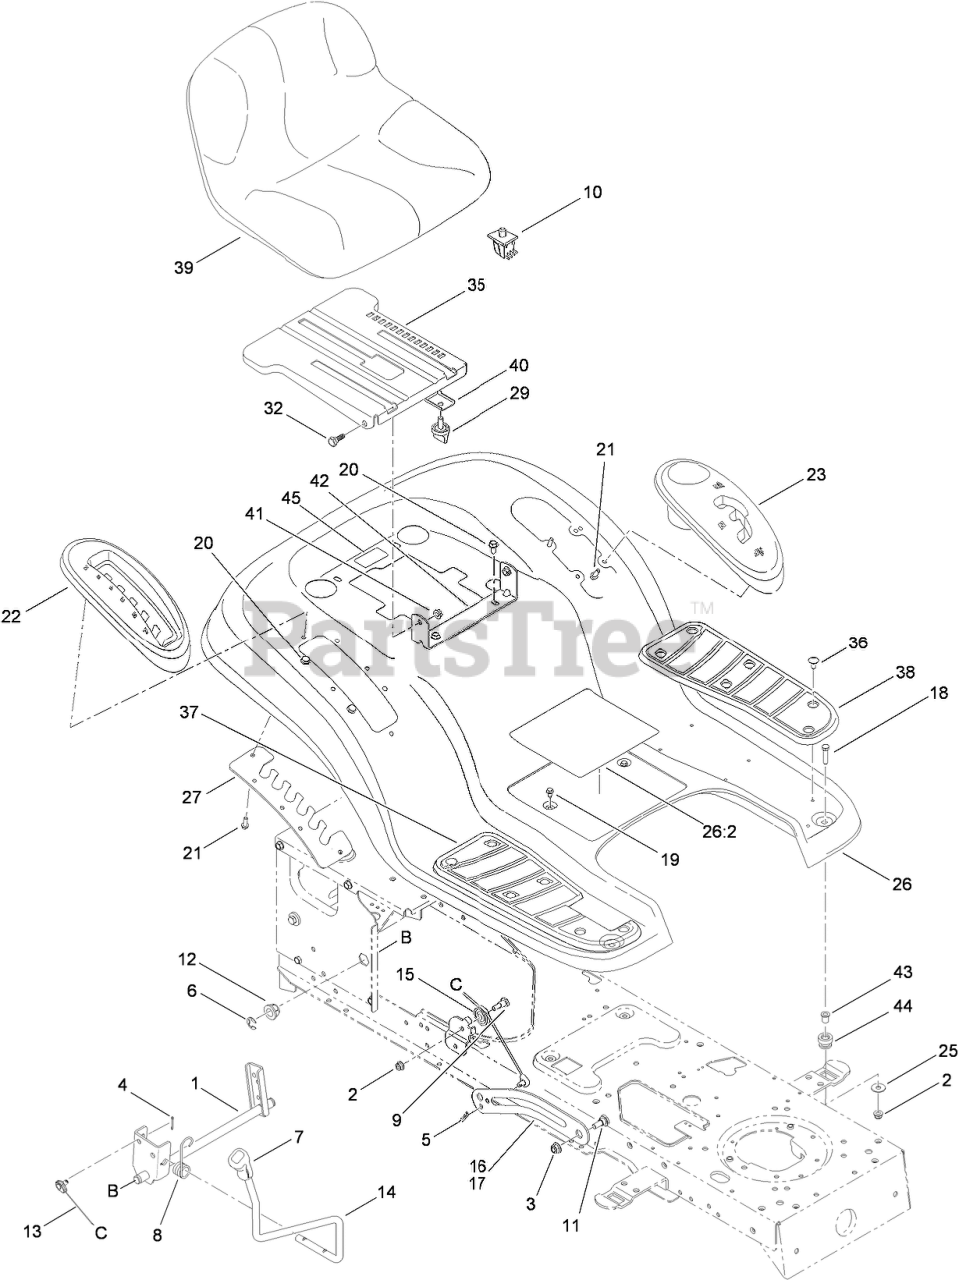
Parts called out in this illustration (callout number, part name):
1	LIFT SHAFT ASM
2	NUT-LOCK, FLANGE
3	NUT-LOCK, FLANGE
4	PIN-COTTER
5	PIN-COTTER
6	RING-E
7	GRIP-HANDLE
8	SPRING-TORSION
9	BOLT-SHOULDER
10	Switch-Seat
11	BOLT-SHOULDER
12	BEARING-FLANGE
13	CABLE-LIFT
14	HANDLE-LIFT
15	PULLEY-ROLLER
16	ARM-LIFT, RH
17	ARM-LIFT, LH
18	SCREW-HH
19	SCREW-HWHTF
20	SCREW-TAP
21	SCREW-TAP
22	COVER-LIFT, LEVER
23	COVER-SHAFT (W/CUP HOLDER)
25	WASHER-FLAT
26	FENDER WITH DECAL
26:2	DECAL-SAFETY
27	BRACKET-ADJUSTING, LIFT
32	BOLT-SHOULDER
35	BRACKET-MOUNT, SEAT
36	CLIP-RATCHET, FASTENER
37	PAD-FOOT, RH
38	PAD-FOOT, LH
40	BRACKET-KNOB, ADJUSTMENT
41	NUT-LOCK, FLANGE
42	BRACKET-PIVOT, SEAT
43	SPACER
44	GROMMET
45	DECAL-TORO HOTLINE
